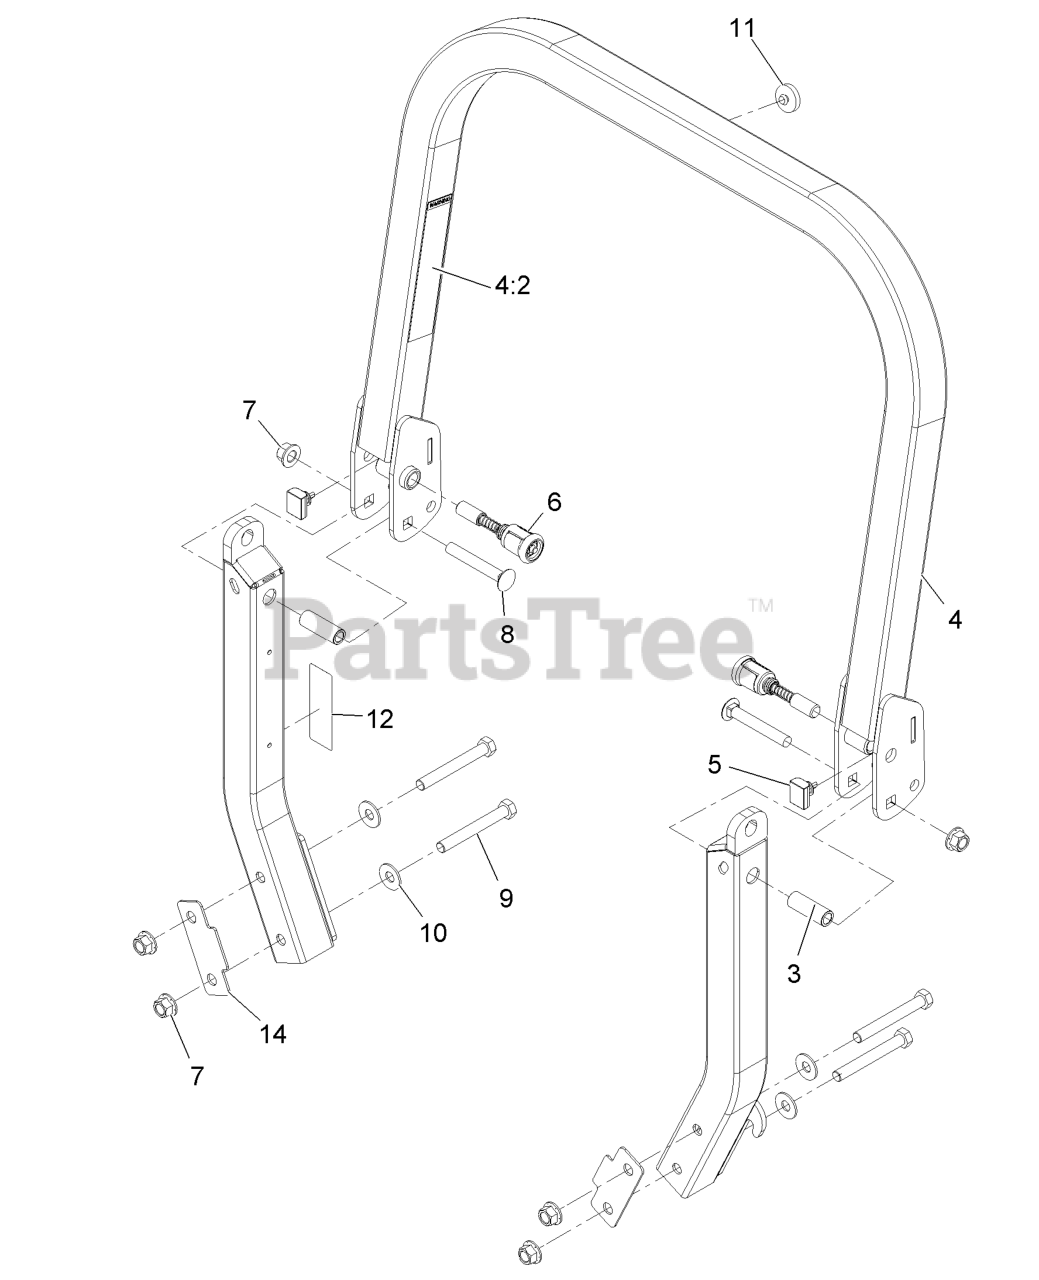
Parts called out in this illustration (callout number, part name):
4	UPPER ROPS ASM
4:2	DECAL-WARNING, FOLDING RO
5	BUMPER-ROPS
6	PIN-SPRING
7	Nut-Lock 1/2-13
8	SCREW-CARR
9	SCREW-HH
10	WASHER-SPRING
11	BUMPER-PUSH-IN, RUBBER
12	DECAL-CAUTION
